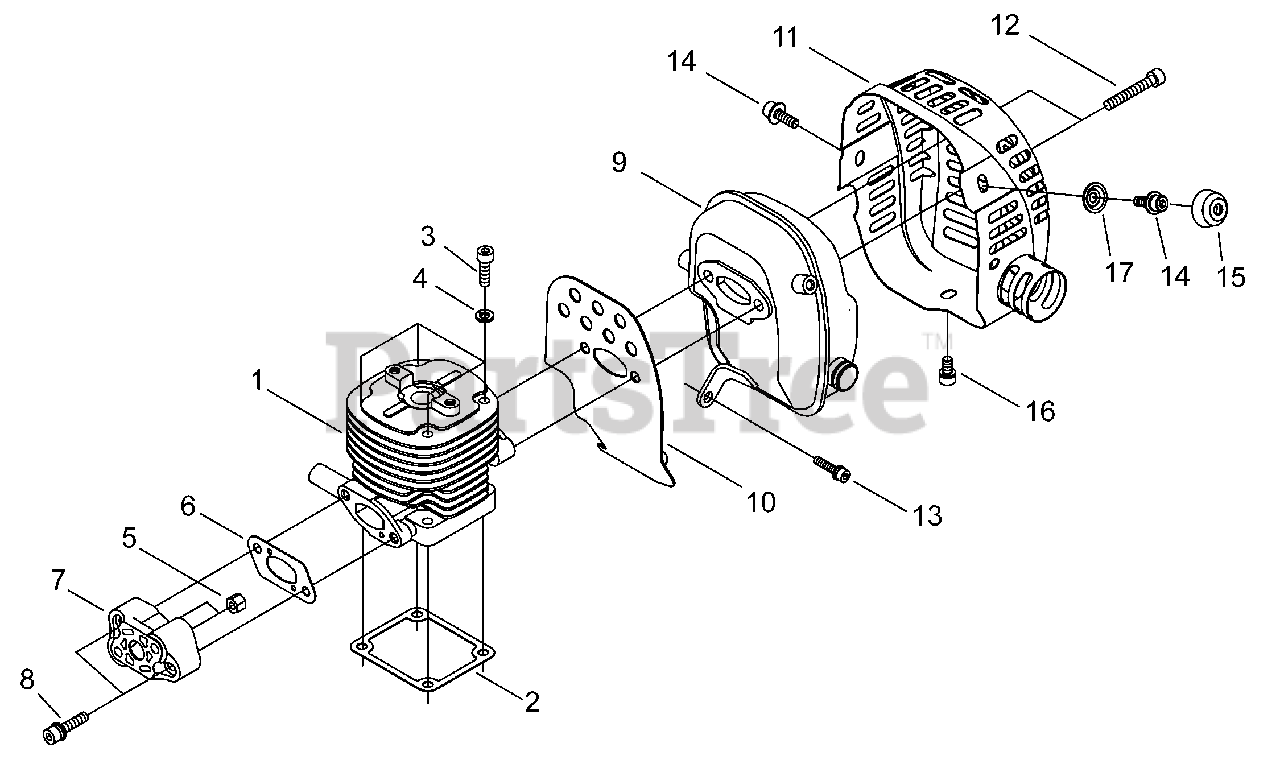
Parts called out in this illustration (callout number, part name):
1	CYLINDER
2	GASKET, CYLINDER
3	BOLT 5×25
4	WASHER, SPRING 5
5	NUT M5×6.3
6	GASKET, INTAKE
7	INSULATOR, INTAKE
8	BOLT M5×25
9	MUFFLER
10	HEAT SHIELD, EXHAUST
11	COVER, MUFFLER
12	BOLT 6×25
13	BOLT M5×12
14	BOLT M5×10
15	COVER
16	BOLT M5×10
17	WASHER
